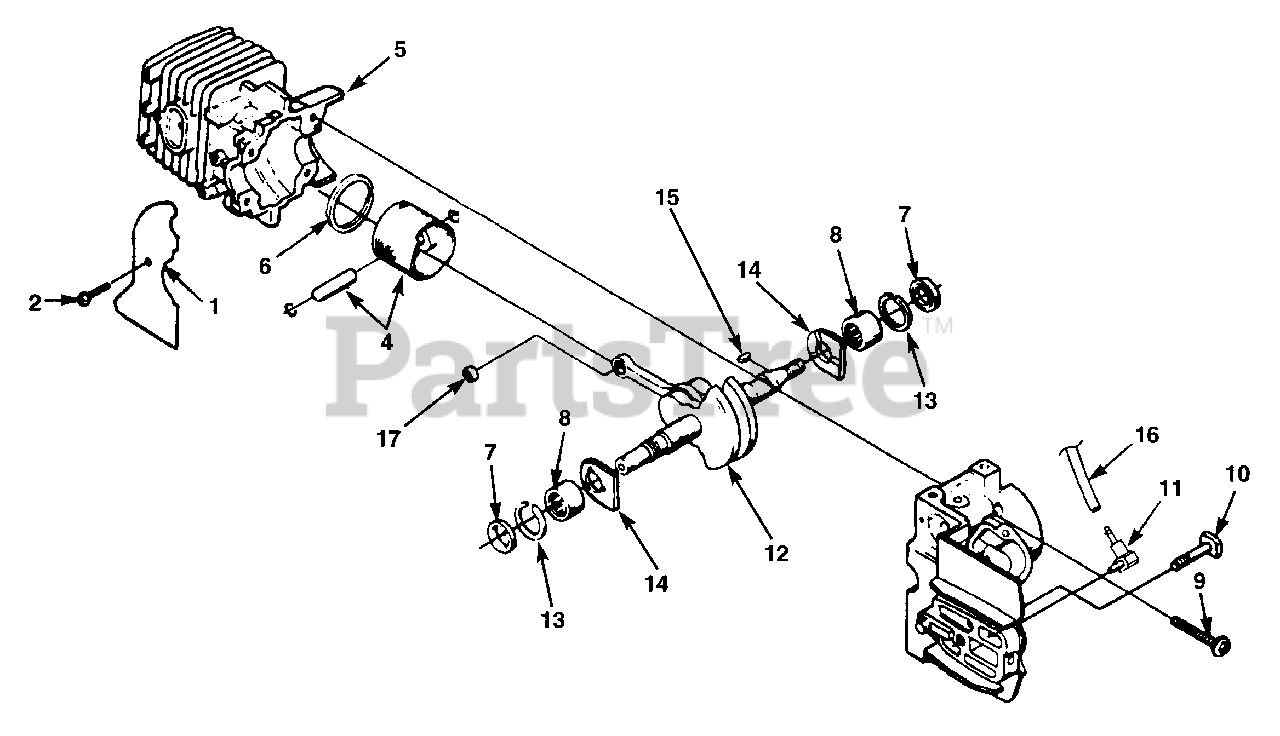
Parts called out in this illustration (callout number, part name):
1	SAW DUST SHIELD
2	SCREW- Tapping (06-32 x 5/16")
4	PISTON & PIN ASSY.
5	CYLINDER
6	RING - Piston
7	SEAL - Shaft
8	BEARING - Needle
9	SCREW - Torx Pan Hd. (10-24 x 1 1/8")
10	BOLT - Guide Bar
11	VALVE - Check
12	CRANKSHAFT - Rod and Bearing
13	SPACER
14	WASHER- Thrust
15	KEY-Woodruff
16	TUBING - Rubber (Oil Line) (8")
17	BEARING - Wrist Pin
